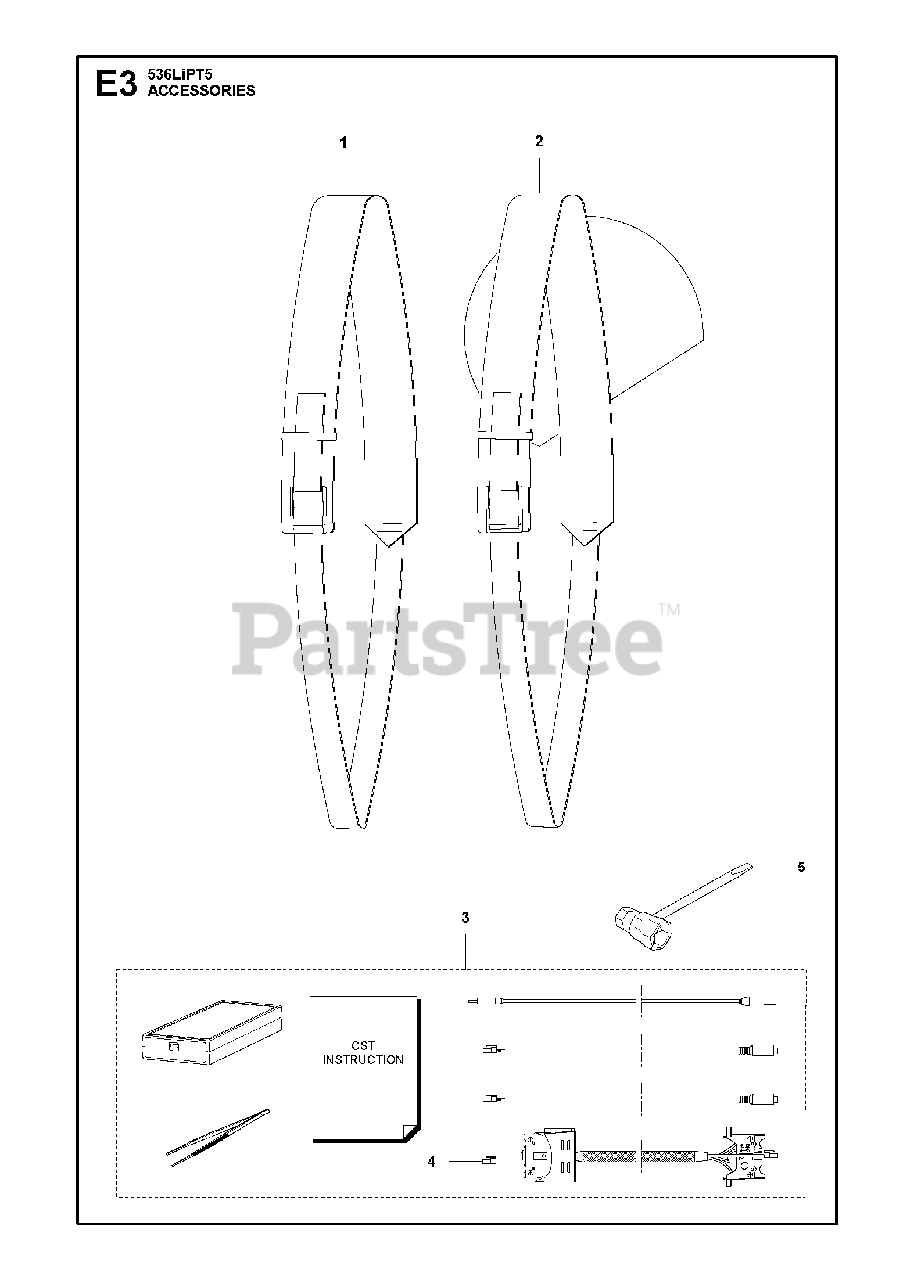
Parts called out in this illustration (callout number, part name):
1	HARNESS WITHOUT HOOK
3	DIAGNOSTIC TOOL KIT
4	WIRING ASSY
5	COMBI TOOL
